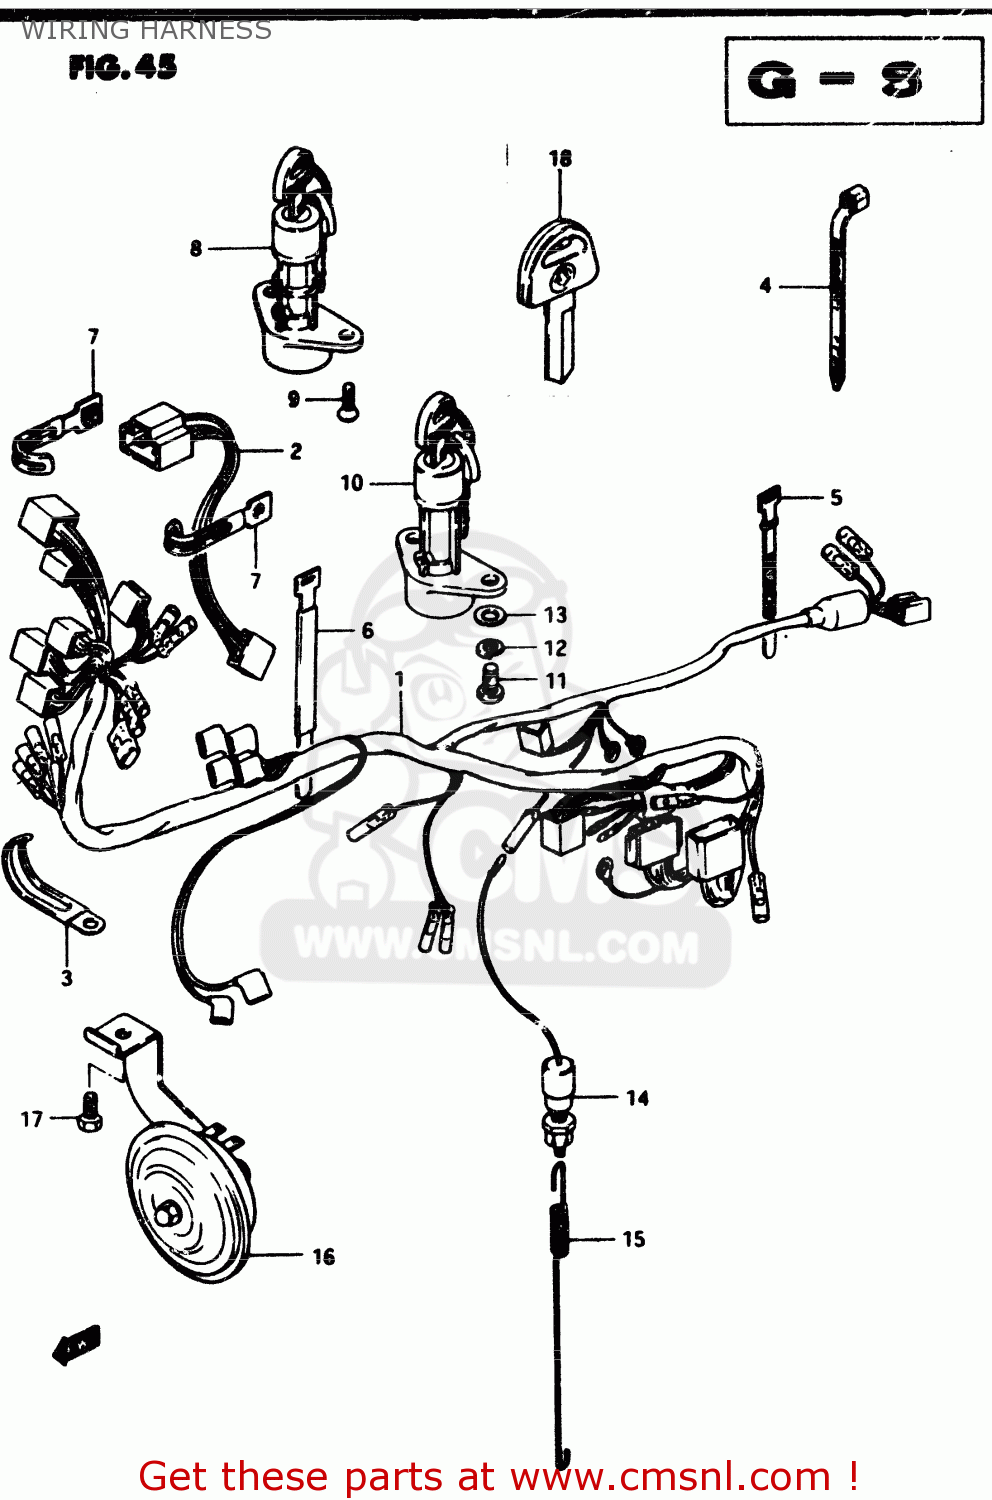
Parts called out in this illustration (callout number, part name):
1	HARNESS,WIRING
2	LEAD WIRE,HEADLAMP
3	CLAMP
4	CLAMP(L:95)
5	CLAMP(L:120)
6	CLAMP
7	CLAMP,WIRING HARNESS
8	SWITCH ASSEMBLY,IGNITION
9	SCREW
10	SWITCH ASSY, IGNITION
11	SCREW
12	LOCK WASHER
13	WASHER
14	SWITCH ASSEMBLY,STOP LAMP
15	SPRING
16	HORN
17	BOLT 8X12
18	KEY,BLANK
